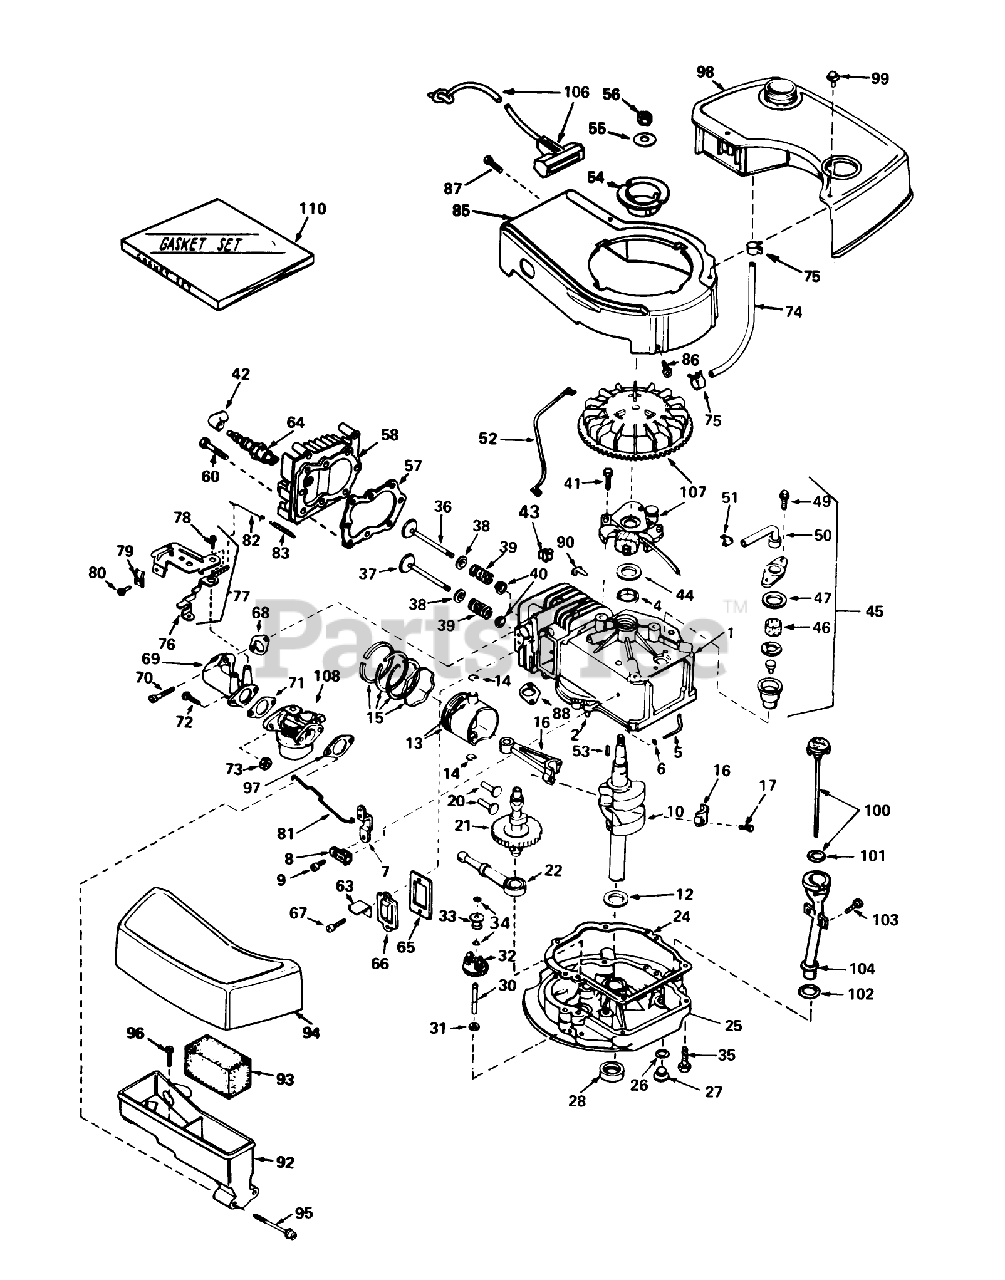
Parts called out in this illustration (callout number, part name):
1	Cylinder Assembly (Incl. Nos. 2, 4 87)
2	Pin-Dowel
4	Seal-Oil
5	Rod, Governor (Incl. No. 36)
6	Washer-Flat
7	Governor Lever
8	Clamp-Lever, Governor
9	Screw
10	Crankshaft
12	Washer-Thrust
13	Piston, Pin Ring Assy. (Incl. Ref. #14 15) (Std.)
13	Piston, Pin Ring Assy. (Incl. Ref. #14 15) (.010 oversize)
13	Piston, Pin Ring Assy. (Incl. Ref. #14 15) (.020 oversize )
14	Ring-Retaining, Piston Pin
15	Ring Set-Piston Std.
15	Ring Set-Piston .010 oversize
15	Ring Set-Piston .020 oversize
16	Rod Assembly, Connecting (Incl. Nos. 17 18)
17	Bolt-Rod, Connecting
20	Lifter-Valve
21	Camshaft(Mech.Comp. Release)
22	Oil Pump ASM
24	Gasket, Mounting
25	Flange Assy., Mounting (Incl. Ref. #26 thru 30)
26	Gasket-Oil Drain
27	Plug Oil Drain
28	Seal-Oil
30	Shaft-Governor
31	Washer-Flat
32	Governor Gear ASM
33	Spool-Governor
34	Ring-Retaining
35	Screw (1/4-20 x 1-1/4)
36	Valve, Intake (Incl. Ref. #38, 39 40) (Std.)
36	Valve, Exhaust (1/32" Oversize) (Incl. Nos. 8, 9 10)
37	Valve, Exhaust (Standard) (Incl. Nos. 8, 9 10)
37	Valve, Exhaust (1/32" Oversize) (Incl. Nos. 8, 9 10)
38	Cap-Upper Valve Spring
39	Spring-Valve
40	Cap-Valve, Spring
41	Screw
42	Cover-Spark Plug
43	Clip, Wire
44	Gasket Stator
45	Breather Assy. (Incl. Ref. #46, 47, 49, 50 51 )
46	Element-Breather
47	Gasket-Breather
49	Screw, Hex Hd. w/Conical
50	Tube, Breaker
51	Clip, Breather
52	Wire, Ground
53	Key, FIywheel
54	Pulley Starter
55	Washer-Spring
56	Hex Nut
57	Oil Fill Tube
58	Head-Cylinder
60	Screw (5/16-18x1-1/2)
63	Retainer Clip
64	Plug, Spark (J17LM or equiv.)
64	Plug, Spark (Champion RCJ-8)
65	Gasket-Breather
66	Cover-Valve
67	Screw
68	Gasket, Intake
69	Pipe, Intake
70	Screw (1/4-20 x 1)
71	Gasket-Carburetor
73	Nut and Lock Washer (1/4-28)
74	Line-Fuel
75	Clamp-Line, Fuel
76	Lever Control
77	Control Assy., Speed (Incl. Nos, 76, 78 89)
78	Screw, Hex Washer Hd Shoulder Self-Tap
79	Conduit
80	Screw (10-32 x 3/8)
81	Link-Throttle
82	Link Governor Spring
83	Spring Governor
85	Housing Blower
86	Screw
87	Screw (10-24 x 9/16)
88	Gasket Exhaust
90	Clip-Wire
92	Body Air Cleaner
93	Filer, Air
94	Cove, Air Cleaner
95	Screw Fil Hd.
96	Screw, Hex Hd.
97	Gasket-Air Cleaner
98	Tank, Fuel
99	Screw (10-32 x 35/64)
100	Dipstick, Oil (Incl. Ref. #101)(Twist Lock)
101	O-Ring
102	Gasket
103	Screw (10-32 x 1/2)
104	Tube-Oil Fill
106	Rope Assy., Starter
107	Magneto
108	Carburetor
110	53024/VAR.16HP O/P
